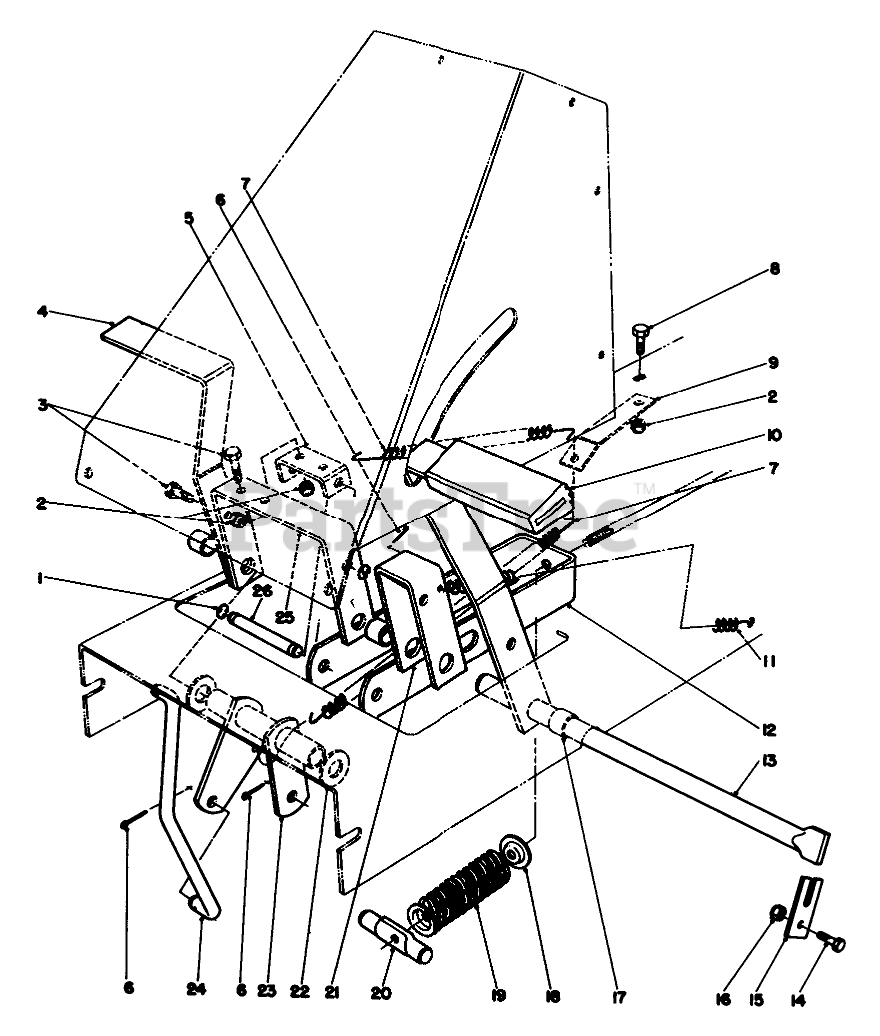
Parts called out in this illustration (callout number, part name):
1	E-RING
2	NUT-LOCK, NI
3	SCREW-HH
4	Pedal
5	Bracket-Brake
6	PIN-COTTER
7	TRACTION SPRING
8	SCREW-HH
9	Bracket-Spring Retaining
10	Pad-Foot Pedal
11	Spring-Tension
12	Bracket-Engagement
13	SHAFT-PEDAL PIVOT
14	SCREW-HH
15	RETAINER-SHAFT
16	NUT-LOCK, CONE
17	SPACER-PEDAL
18	RETAINER-SPR. TOP
19	SPRING-COMPRESSION
20	SHAFT-DECK ADJ.
21	Bracket-Clutch Pedal
22	WASHER-FLAT
23	Tube-Pivot
24	Arm-Engagement
25	Bracket-Brake Pedal
26	Pin-Clevis
